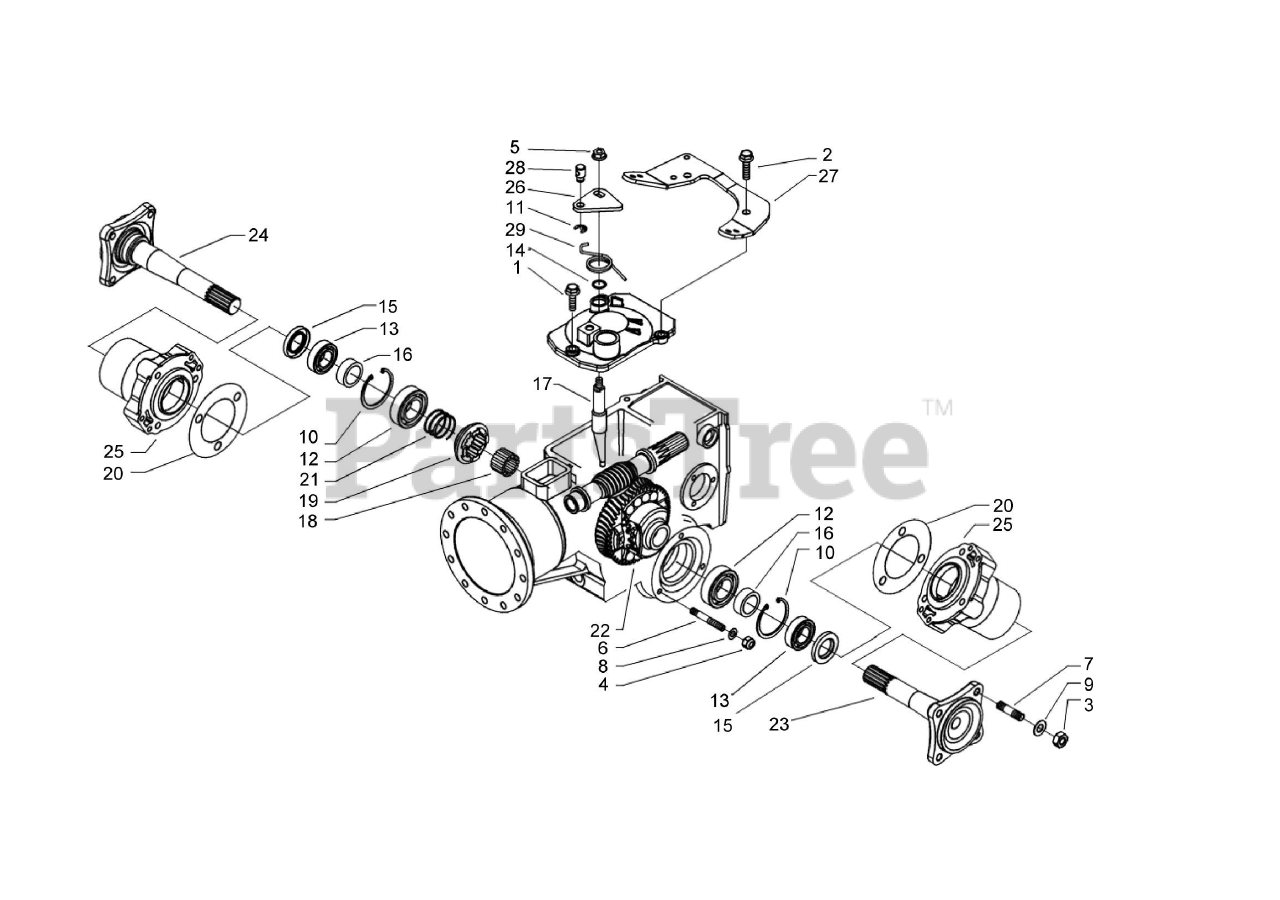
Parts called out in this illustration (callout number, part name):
1	SCREW TE M8X25
2	SCREW
3	NUT M10 UNI 5588-6S
4	LOCKNUT M8 STANDARD DIN985ZC
5	LOCKNUT M8 FLANGED
6	STUD M8X46X20X12 GRADE 8
7	STUD M10X40X24X12 GRADE 8
8	WASHER LOCK B 8.4 DIN 137A ZINC
9	WASHER WAVEY B 10.5 DIN 1
10	SNAP RING INTERNAL D 47 DIN 472
11	SPLIT RING RS 6 DIN 679
12	BEARING 25X15X15 6205
13	BEARING 25X47X12 6005 ZC
14	0 RING 2056 14.00X1.78
15	OIL SEAL 30X40X7
16	RING HALF AXLE
18	SPACER GEAR FOR DIFFERENTIAL
19	COUPLING FRONT
20	GASKET JOINT
21	SPRING
22	DIFFERENTIAL
23	AXLE SHAFT
24	AXLE LONG HALF
25	HUB FOR HALF AXLE
26	LEVER
29	SPRING
